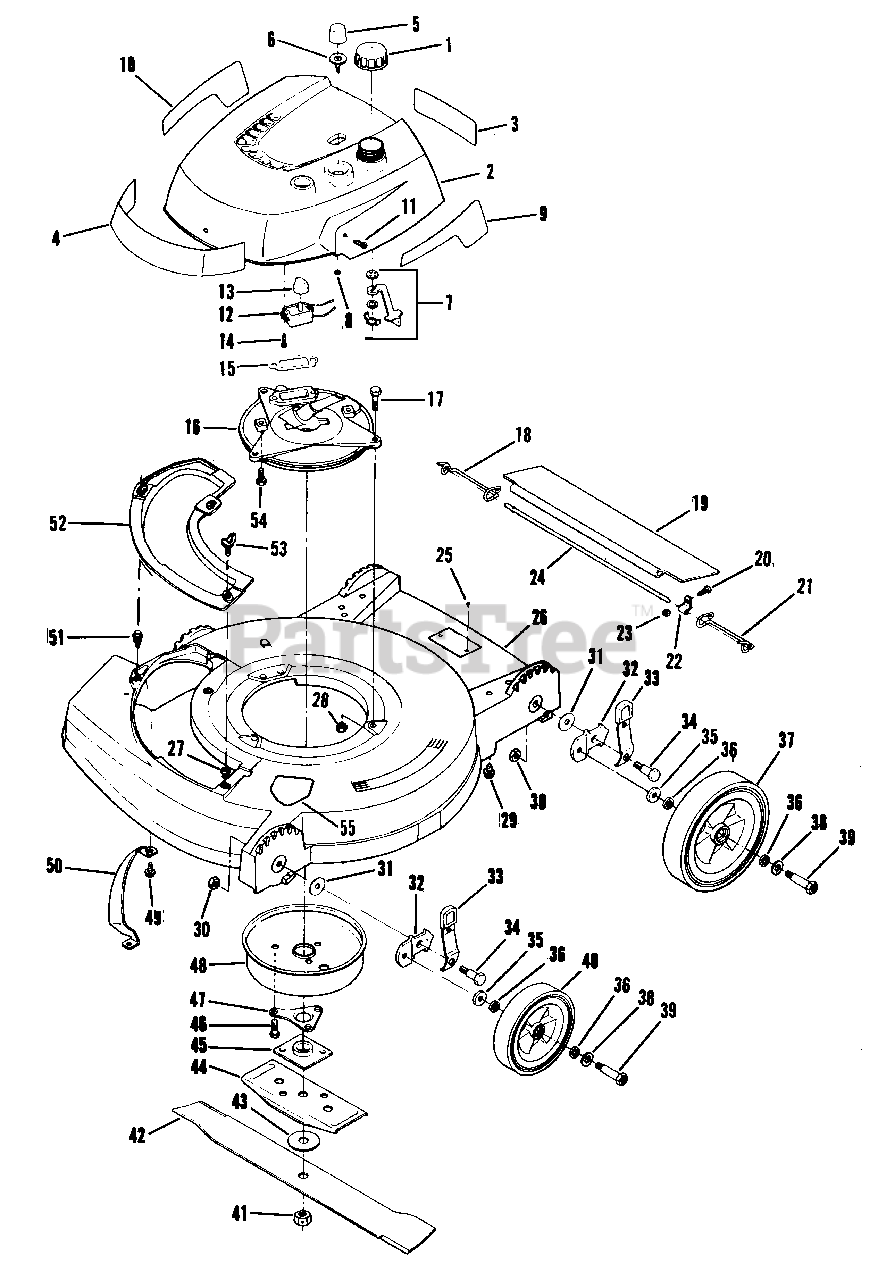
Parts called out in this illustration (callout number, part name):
1	Fuel Cap
2	Shroud-Engine
3	Decal-Instructions
4	Decal-Lawn-Boy
5	Bulb-Primer
6	Base-Primer
7	Fuel Shut-Off Assembly
8	Nut
9	Decal-L.H. 21"
10	Decal-R.H. 21"
11	Screw-Shroud Mounting
12	Switch Assembly
13	Knob
14	Screw
15	Gasket-Exhaust
16	Plate-Muffler
17	Screw-Muffler Plate to Housing
18	Spring-R.H.
19	Shield-Trailing 21"
20	Screw
21	Spring-L.H.
22	Clamp
23	Nut
24	Rod-Trailing Shield 21"
25	Screw-Model Plate Mounting
26	Housing-21"
27	Grommet
28	Nut-Muffler Plate to Housing
29	Screw-Handle Bracket to Housing
30	Nut
31	Washer
32	Bracket-Wheel Height Adjustment
33	Knob & Spring Assembly
34	Shoulder Bolt
35	Washer
36	Washer-Felt
37	Wheel-Rear
38	Washer
39	Bolt-Wheel
40	Wheel-Front
41	Nut-Blade
42	Blade-21"
43	Washer-Blade
44	Stiffener-Blade
45	Collar & Plate Assembly
46	Screw
47	Support-Crankshaft
48	Muffler Cover Assembly
49	Screw-Sems
50	Toe Bar-21"
51	Screw-Sems-Plate & Chute Mounting
52	Cover Plate
53	Wing Screw
54	Screw-Muffler Plate to Block
55	Decal-Blade Contact Warning
